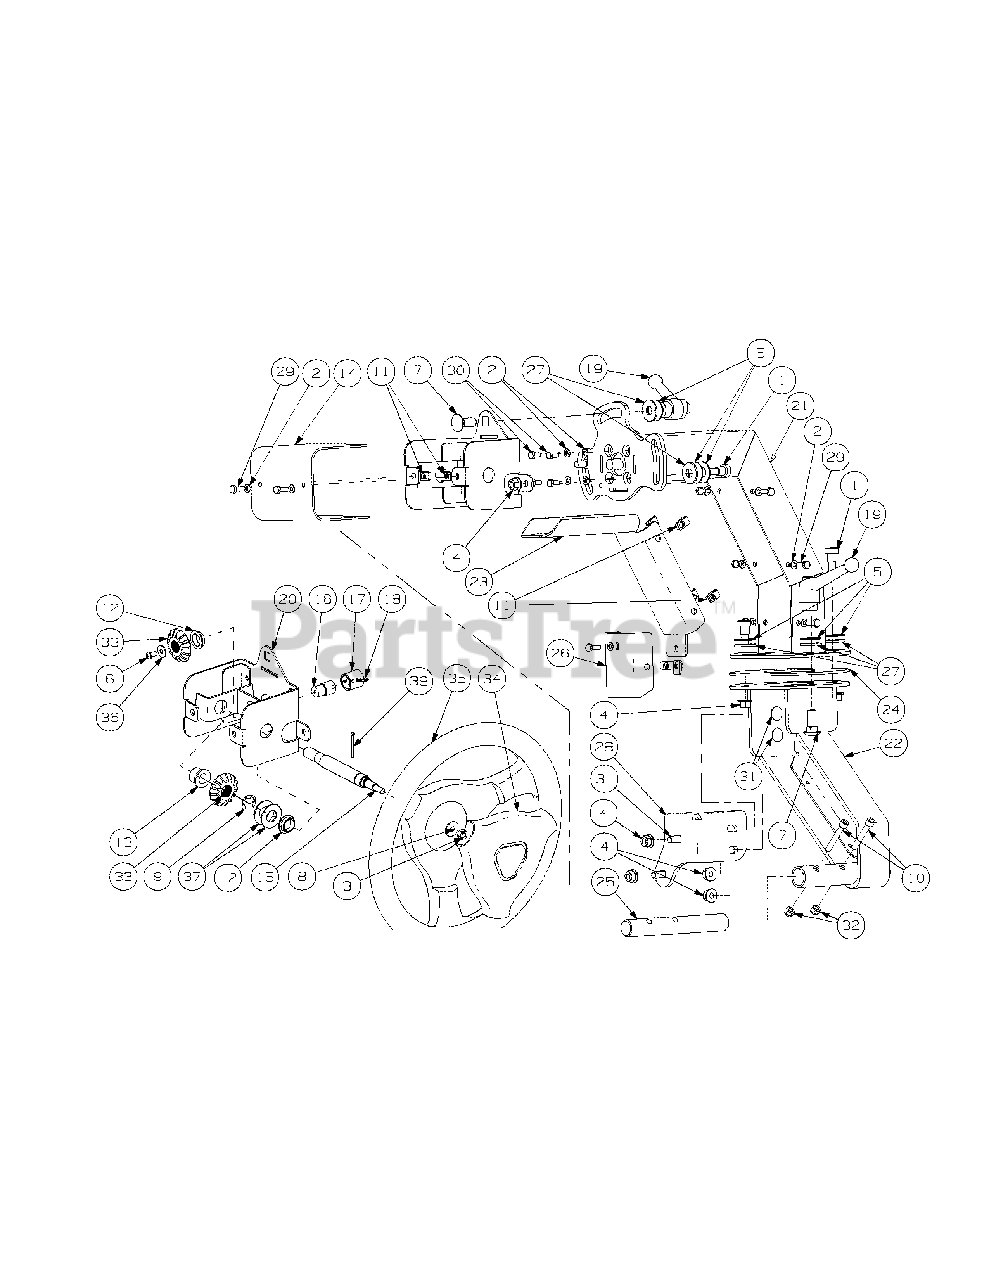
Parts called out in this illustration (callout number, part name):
1	Shoulder Bolt, 1/2 x 1/2
2	Lock Washer, 1/4
3	Hex Nut, 5/16-24
4	Hex Nut, 3/8-16, Flange Lock
5	Washer, 1/2, SS
6	Capscrew, 1/4-20 x .500
7	Carriage Bolt, 1/2-13 x 1-1/4
8	Washer, .325 x .930 x .045
9	E-Clip, 3/4 Dia.
10	Socket Head Capscrew, 5/16-18 x 2.00
11	U-Nut, 1/4-20
12	Flange Bearing, .752 x 1.125 x .305
13	Flange Bearing, .630 x .875 x .75
14	Steering Box Cover
15	Steering Shaft
16	Steering Valve Shaft
17	Steering Valve Hub
18	Heavy Duty Pin, 3/16 x 1.0
19	Steering Column Adjustment Lever
20	Steering Housing Assembly
21	Steering Column Assembly, Upper
22	Steering Column Assembly, Lower
23	Steering Column Cover, Large
24	Wear Plate
25	Pin, 1.0 Dia x 7.50
26	Steering Column Cover, Small
27	Washer, .531 ID x 1.25 OD x .100
28	Steering Column Support Bracket
29	Screw, Hex, Cap, 1/4-20 x .75
30	HHCS, M6-1.00, 14mm
31	Carriage Bolt, 3/8-16 x 1-1/4
32	Nut, 5/16-18, Nylock
33	Splined Bore Miter Gear
34	Steering Wheel Cover
35	Steering Wheel
36	Washer, .28 x .74 x .063
37	Washer, .76 x 1.49 x .06
38	Cotter Pin, 1/8 x 1.25
